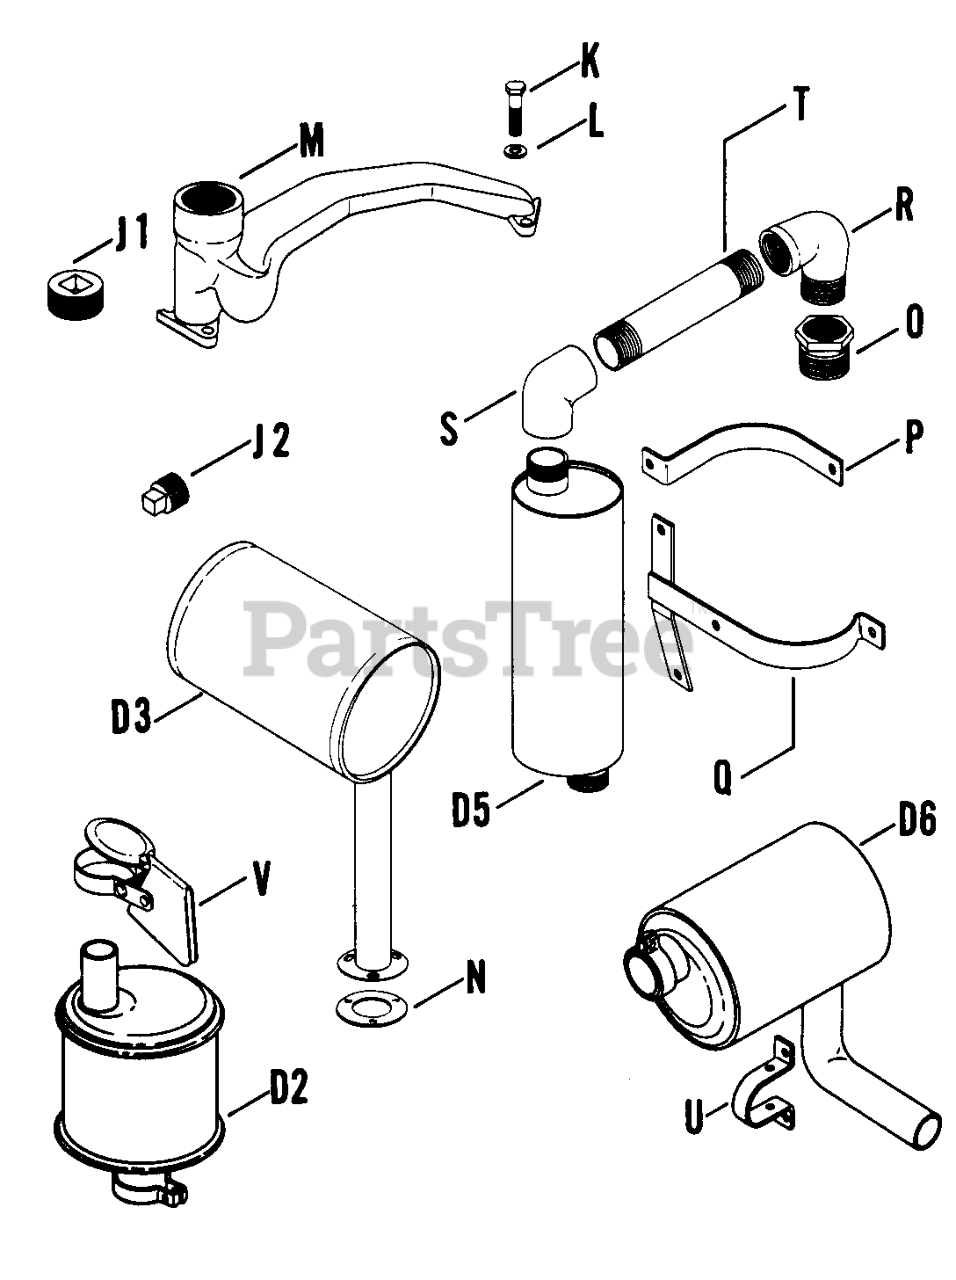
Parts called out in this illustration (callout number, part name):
D2	MUFFLER - DISCONTINUED
K	SCREW - USE 41 086 02
L	WASHER, FLAT 13/32"
L	WASHER - USE 41 468 01
V	CAP - DISCONTINUED
